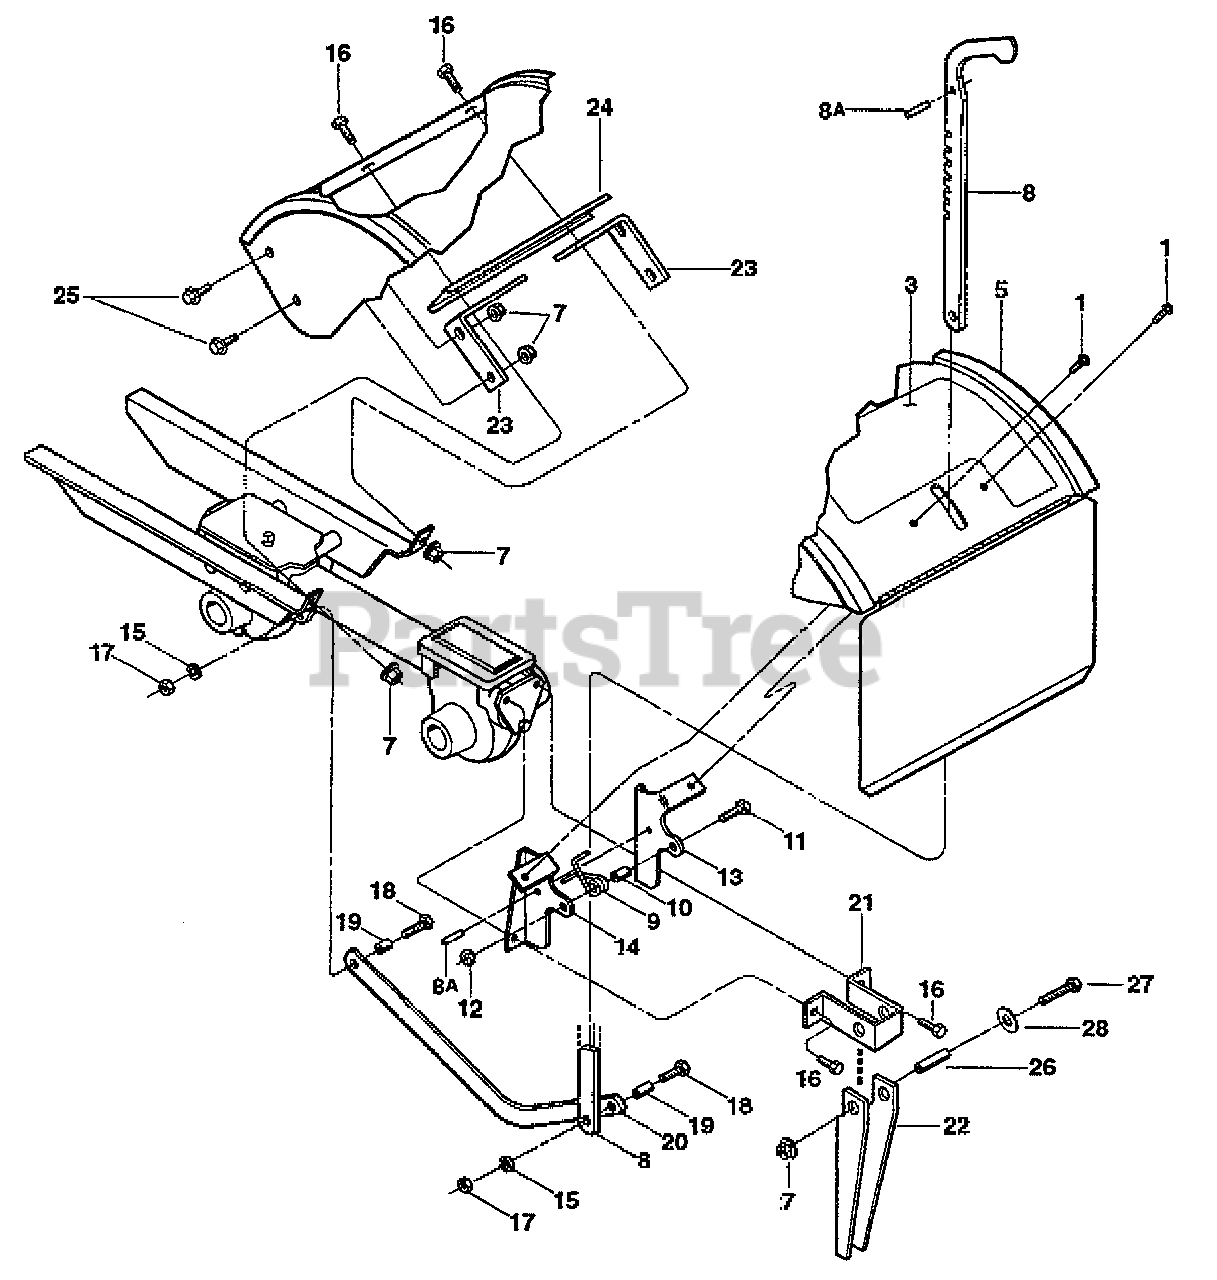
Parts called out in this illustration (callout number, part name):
1	Flange Screw, Self-Tapping, 1/4-20 x 1/2
3	Decal, Hood
5	Tine Hood
7	Flange Lock Nut, 5/16-18
8	Depth Regulator Lever
8A	Spiral Pin
9	Spring, Depth Regulator
10	Spacer
11	Hex Hd. Screw, 1/4-20 x 1
12	Hex Lock Nut, 1/4-20
13	Hood Bracket, Right Hand
14	Hood Bracket, Left Hand
15	Lockwasher, 5/16
16	Flange Hd. Screw, 5/16-18 x 1
17	Hex Nut, 5/16-18
18	Hex Hd. Screw, 5/16-18 x 1-1/4
19	Bushing
20	Drag Bar
21	Bracket, Stop
22	Reverse Arm (Drag Stake)
23	Bracket, Hood Support
24	Bracket, Support Channel
25	Hex Hd. Screw, 5/16-18 x 5/8
27	Hex Hd. Screw, 5/16-18 x 2-1/4
28	Washer, 5/16 I.D.
